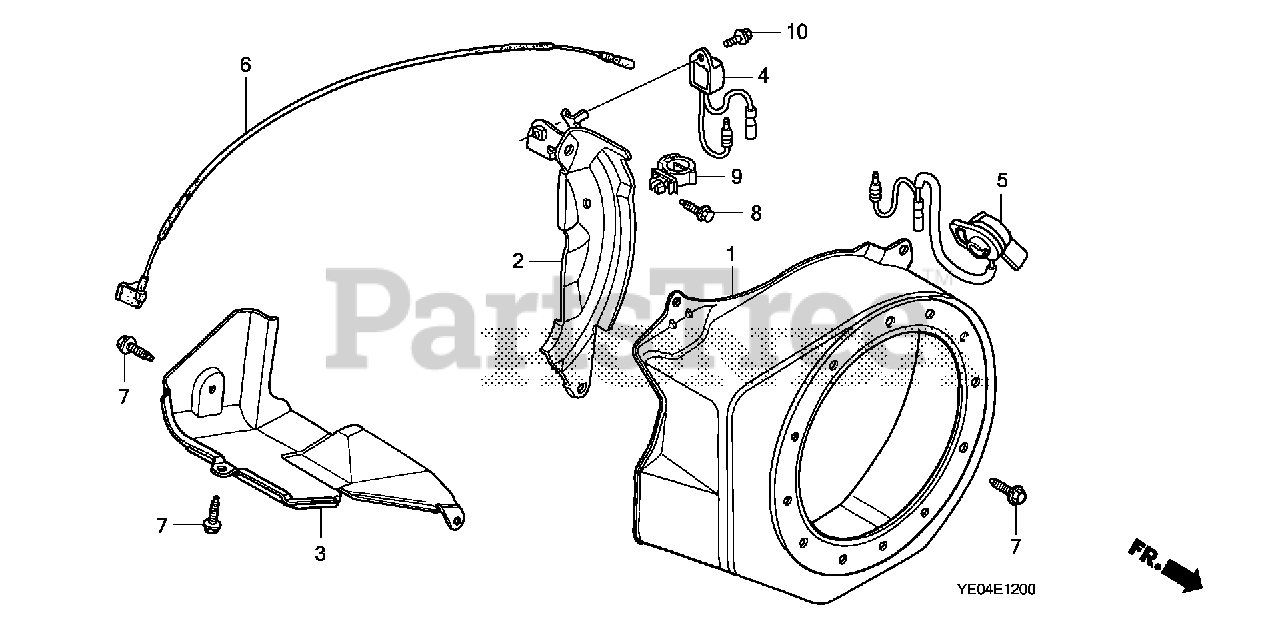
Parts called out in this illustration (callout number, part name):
1	COVER, FAN *R280* (POWER RED)
2	PLATE, SIDE (OIL ALERT)
3	SHROUD
4	ALERT UNIT, OIL
5	SWITCH ASSY., ENGINE STOP (TOYO DENSO)
5	SWITCH ASSY., ENGINE STOP
5	SWITCH ASSY., ENGINE STOP (MINDA)
6	WIRE, STOP SWITCH (370MM)
7	BOLT, FLANGE (6X12) (CT200)
8	BOLT, FLANGE (6X20) (CT200)
9	CLIP, HARNESS
10	BOLT, FLANGE (6X8)
